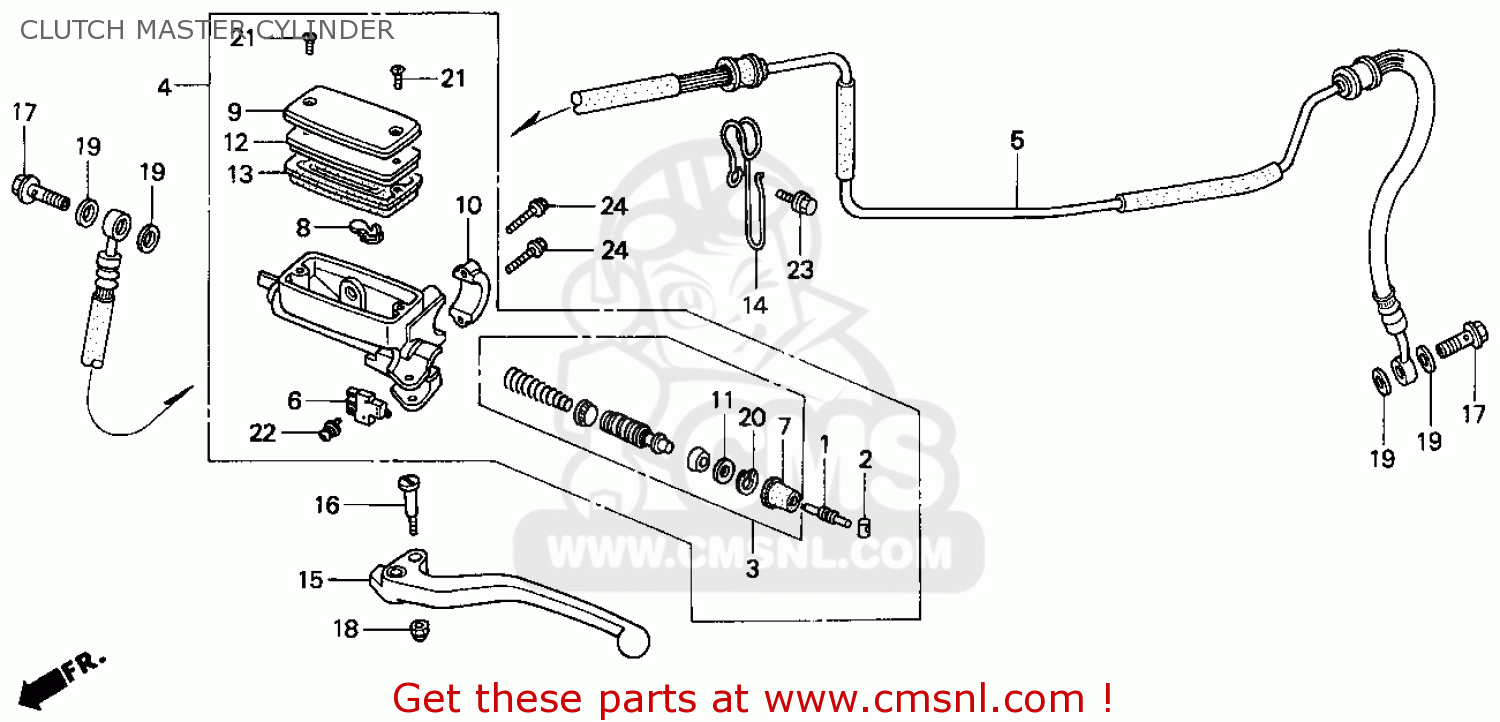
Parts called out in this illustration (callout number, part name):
1	ROD,PUSH
2	BUSH
3	PISTON SET,CLUTCH
4	M/C SUB ASSY,CLUT
5	PIPE COMP.,CLUTCH
6	SW.ASSY.,CLUTCH
7	BOOT COMP.
8	PROTECTOR
9	CAP
10	HOLD,MAS.CYLINDER
11	PLATE,STOPPER
12	PLATE,DIAPHRAGM
13	DIAPHRAGM
14	CLAMP,CLUTCH HOSE
15	LEVER COMP.,L.HAN
16	BOLT,HNDL PIVOT
17	BOLT,OIL,10X22
18	NUT,CAP,6MM
20	CIR CLIP,INTERNAL
21	SCREW,FLAT,4X12
22	SCREW-WASH,4X12
23	BOLT,FLANGE 6X14
24	BOLT,FLANGE,6X22
